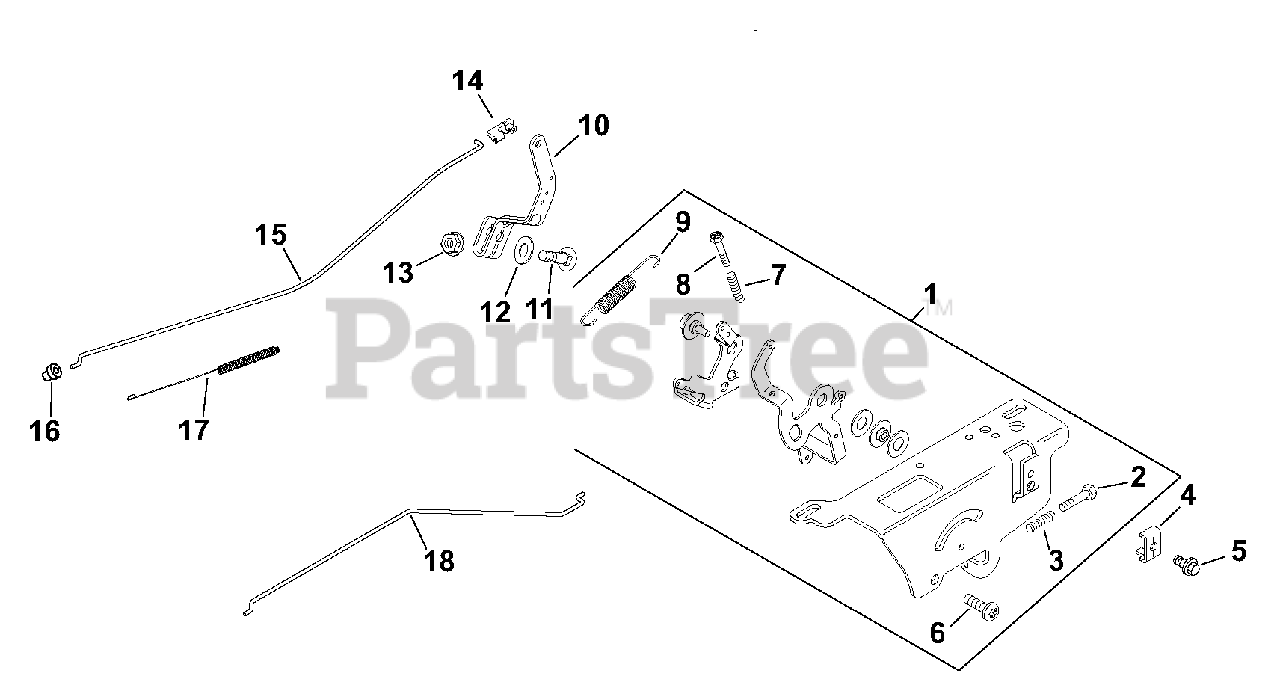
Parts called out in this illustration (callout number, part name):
1	Kit, Speed Control Assembly
2	Screw, Phl Thd Frm M4x0.7x25
3	Spring, Speed Control (Short)
4	Clamp, Cable
5	Screw, Lbd Thd Frm M5x0.8x16
6	Screw, Lbd Skt M6x1.0x20
7	Spring, Speed Control (Short)
8	Screw, Phl Thd Frm M4x0.7x25
9	Spring, Governor
10	Lever, Governor
11	Bolt, Rd Hd Sq Nck 1/4-20x1"
12	Washer, Int Tooth Lock 1/4"
13	Nut, Hex Flg 1/4-20"
14	Bushing, Throttle Linkage
15	Linkage, Throttle
16	Bushing, Linkage Retaining
17	Spring, Linkage
18	Linkage, Choke
